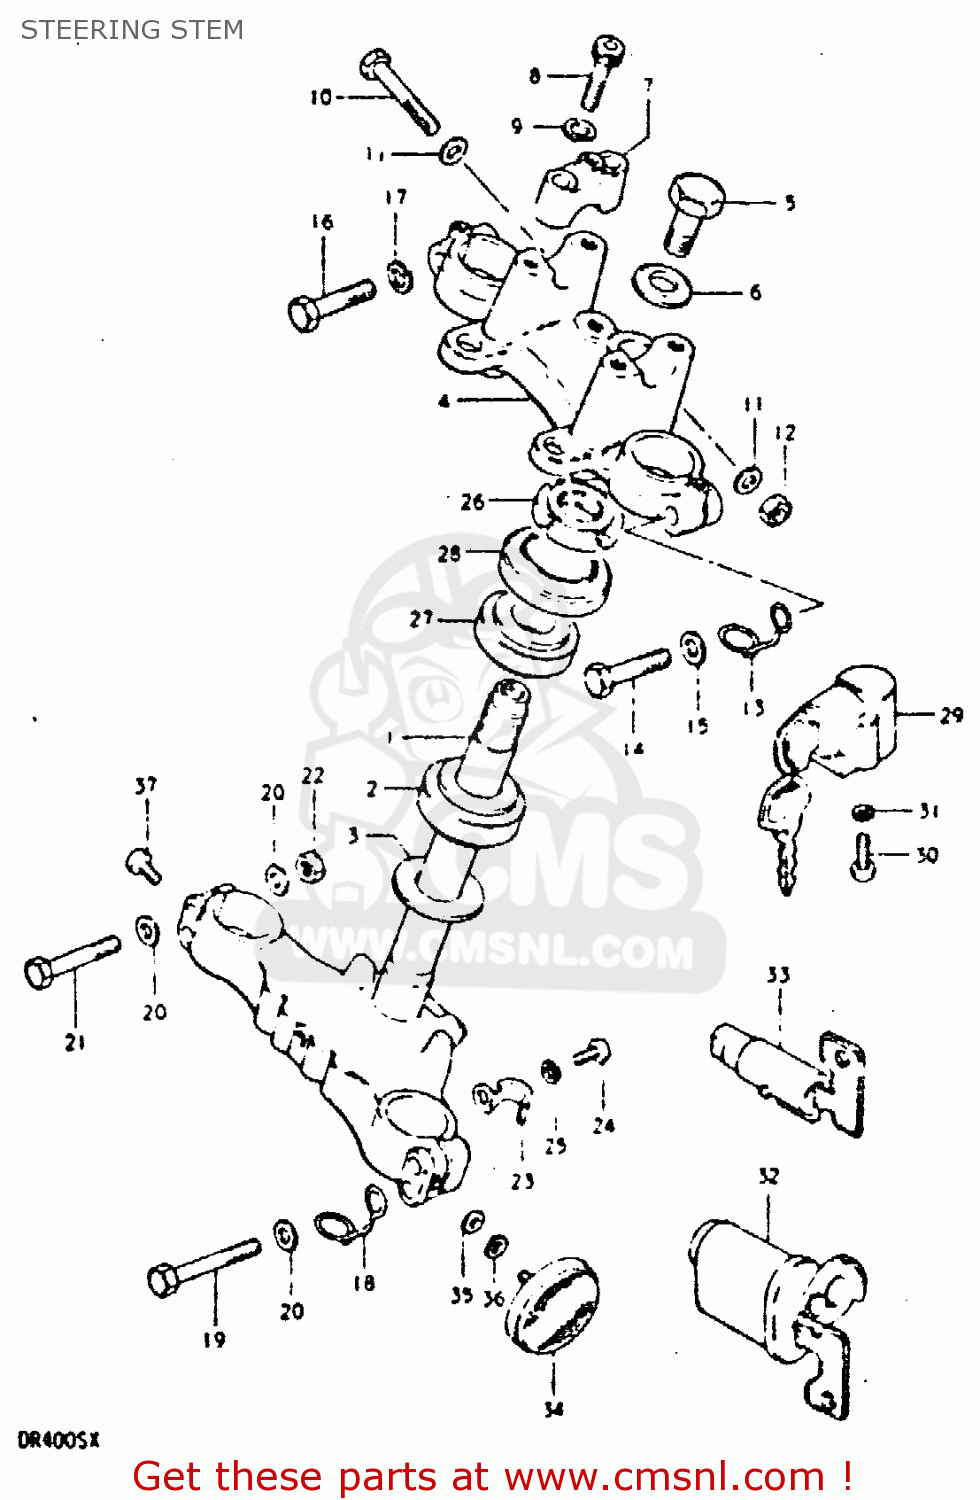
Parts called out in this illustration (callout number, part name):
1	STEERING STEM
2	BEARING
3	WASHER,THRUST
4	HEAD,STEERING STEM
5	BOLT,STEERING STEM HEAD
6	WASHER
7	CLAMP,HANDLE HOLDER UPR
8	BOLT 8X35
9	LOCK WASHER
10	BOLT 8X55
11	WASHER
12	NUT
13	CLIP
14	BOLT 10X40
15	WASHER
16	BOLT 10X40
17	LOCK WASHER
18	GUIDE,CABLE
19	BOLT
20	WASHER
21	BOLT 8X55
22	NUT
23	CLIP,BRAKE CABLE
24	SCREW
25	LOCK WASHER
26	NUT,STEERING STEM(25X44X10)
27	TAPER,ROLLER BEARING
28	DUST SEAL,STEERING,UPPER
29	LOCK ASSEMBLY,STEERING
30	SCREW
31	LOCK WASHER
